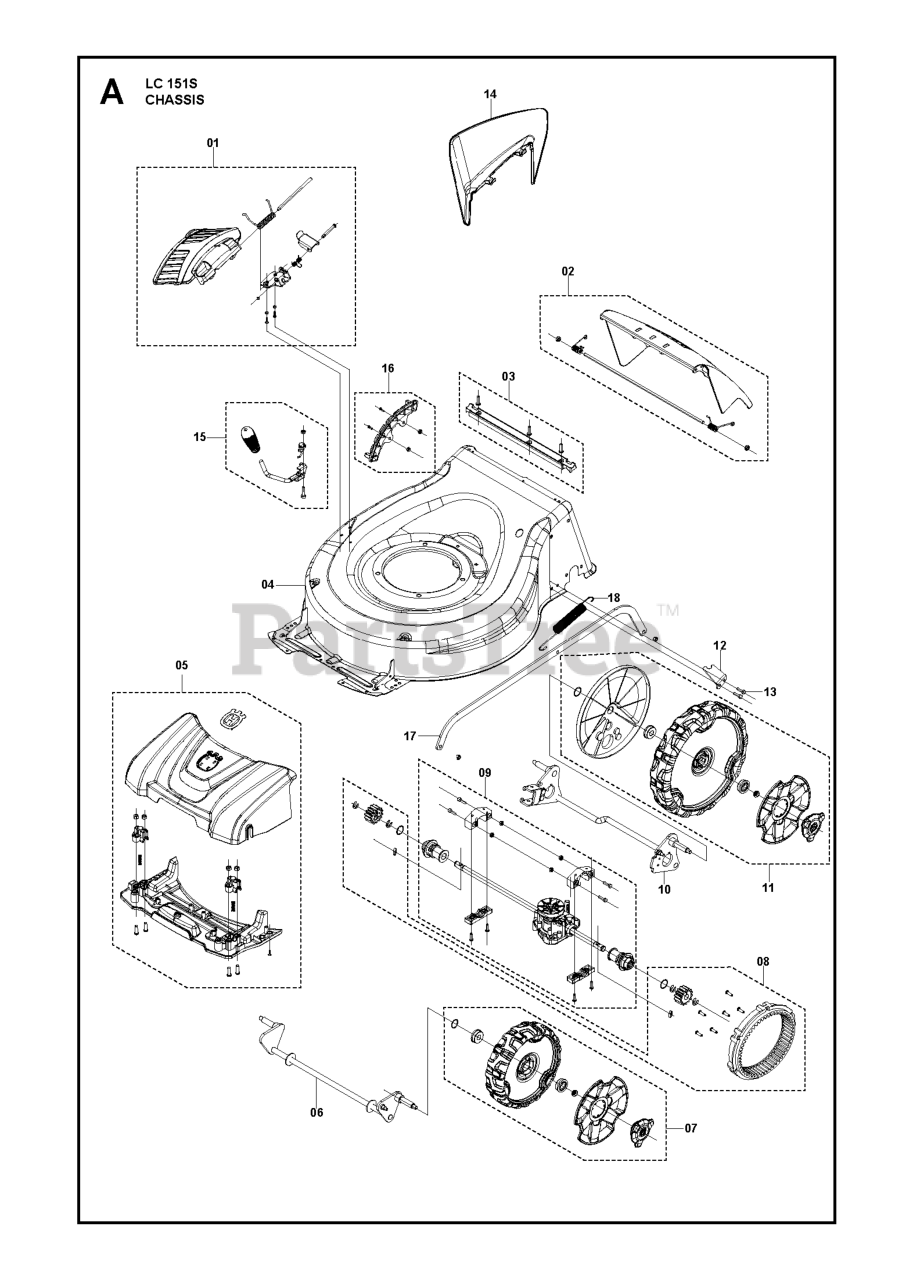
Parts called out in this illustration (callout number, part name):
3	Seals
7	Wheels
9	Transmissions
